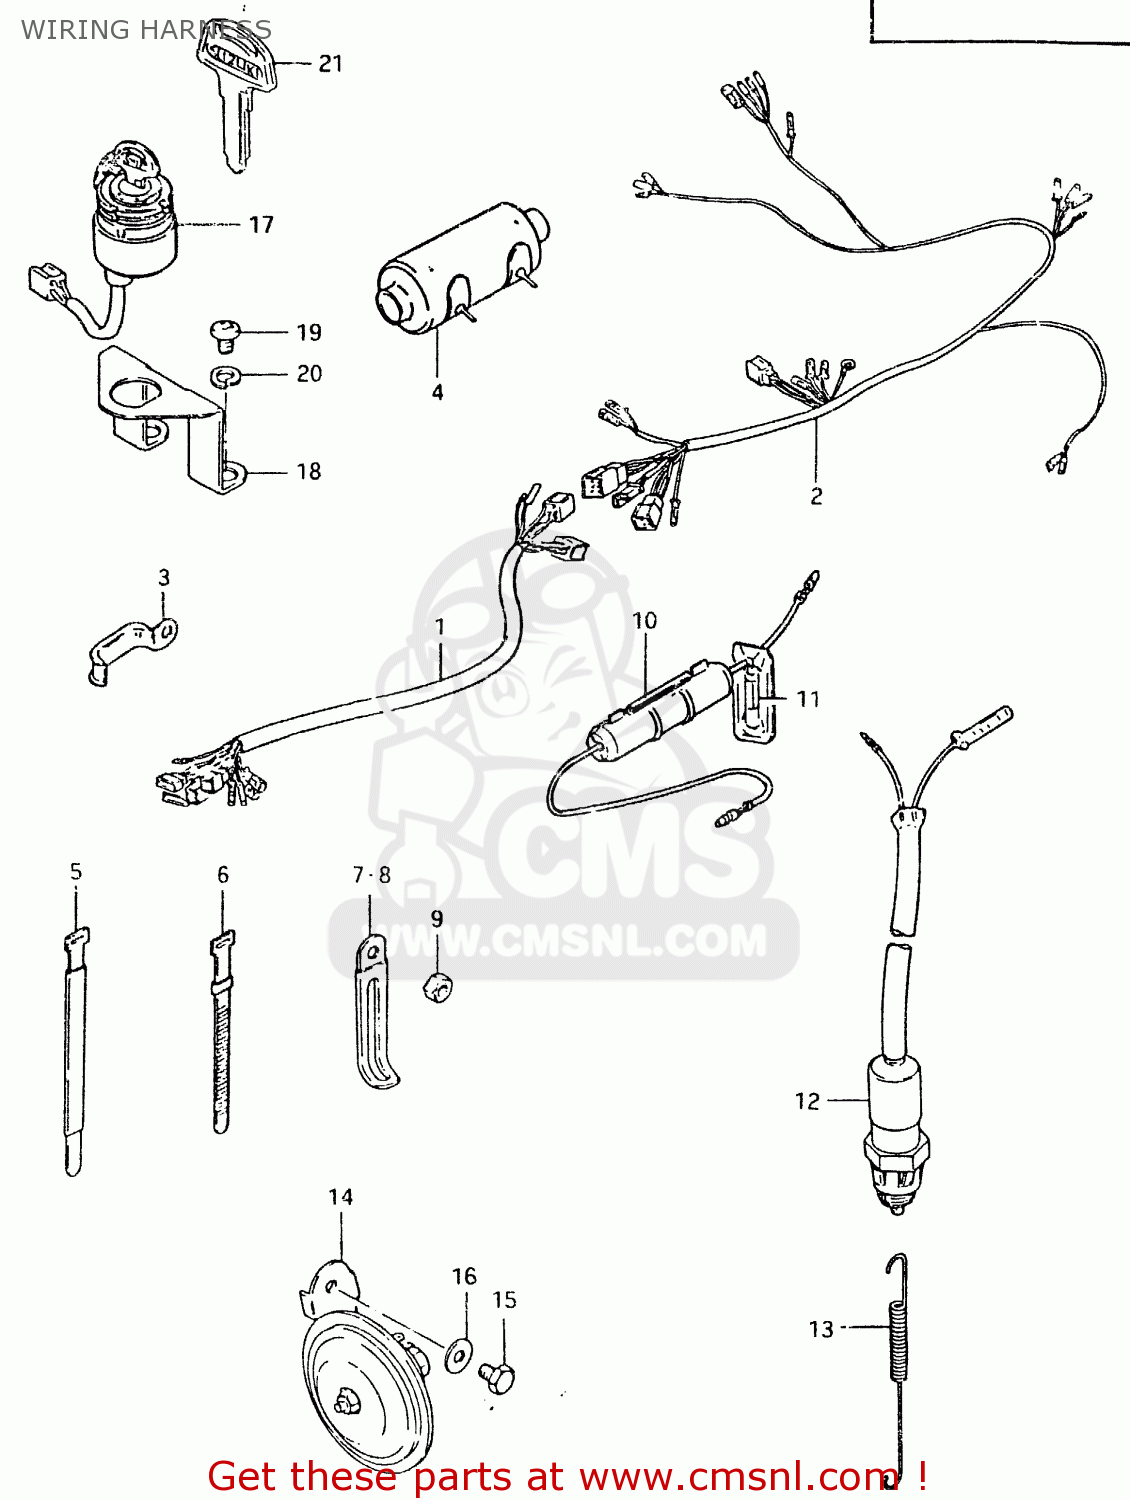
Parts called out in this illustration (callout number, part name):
1	HARNESS,WIRING
2	WIRING HARNESS NO.2
3	CLAMP
4	BOOT,WIRING HARNESS
5	CLAMP
6	CLAMP(L:120)
7	CLAMP
8	CLAMP
9	NUT
10	BOX ASSEMBLY,FUSE
11	FUSE(10A)
12	SWITCH ASSEMBLY,STOP LAMP
13	SPRING
14	HORN ASSEMBLY
15	BOLT
16	WASHER
17	SWITCH ASSY, IGNITION
18	BRACKET,IGNITION SWITCH
19	SCREW
20	LOCK WASHER
21	KEY,BLANK
